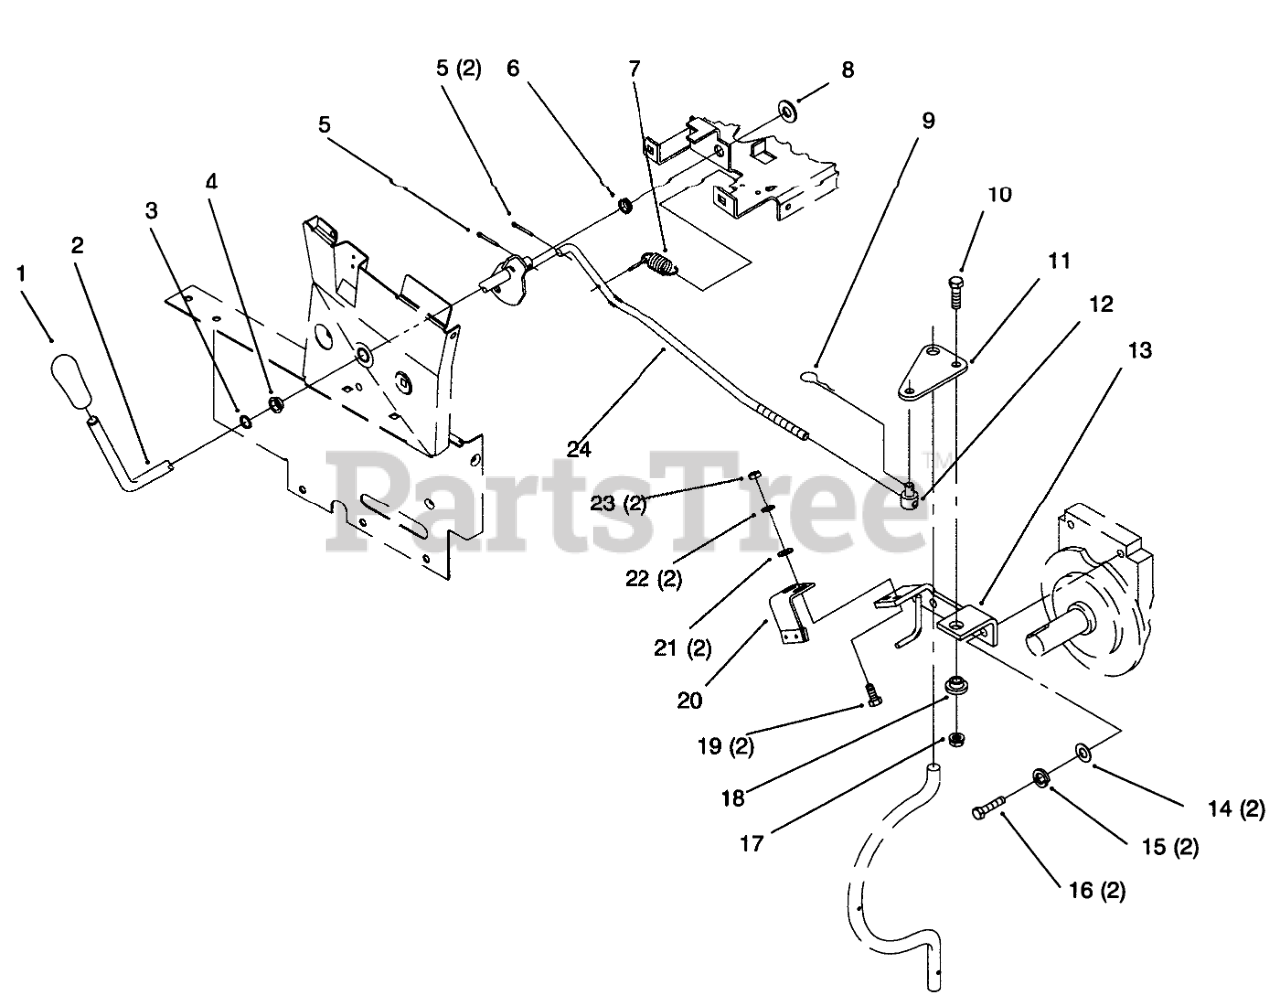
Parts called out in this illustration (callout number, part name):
2	PTO CLUTCH LEVER ASM
3	RING-EXT GRIP
4	BUSHING-NYLINER
5	PIN-COTTER
6	NYLINER BUSHING
7	SPRING
8	SHIM-WASHER
9	PIN-HAIR
10	SCREW-HH
11	PLATE
12	TRUNNION
13	Bracket
14	WASHER-FLAT
15	WASHER-LOCK
16	SCREW-HH
17	NUT-LOCK, NI
18	SPACER-LIFT LINK
19	SCREW-CARR
20	ASM-Bracket
20	BRAKE ASM
21	WASHER-FLAT
22	WASHER-LOCK
23	NUT-JAM
24	ROD-PTO CLUTCH
